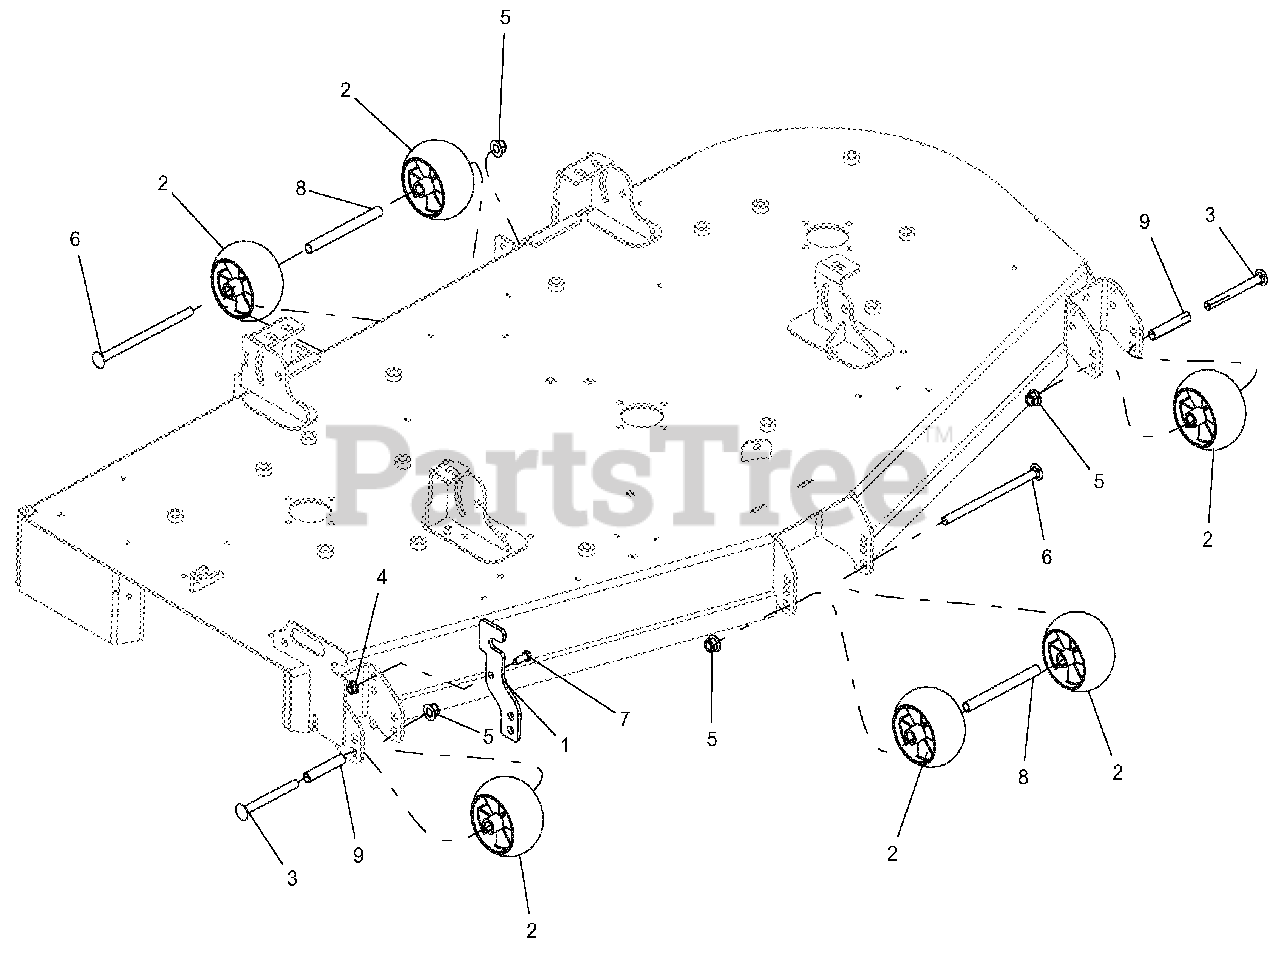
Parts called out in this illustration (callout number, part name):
1	CHUTE STORAGE BRACKET-RED
2	ANTI-SCALP WHEEL - 5X3 CTR
3	BLT-RDHDSQNK .50-13X5.00 G5 YWZC
4	NUT-LK-NYL-FLG .38-16 YWZC
5	NUT-LK-NYL-FLG .50-13 YWZC
6	BLT-RDHDSQNK .50-13X8.50 Y
7	BLT-HEX .38-16X1.00 GR5 YWZC
8	SPACER, .510 X .625 X 6.50
9	SPACER, .510X.625X3.35
